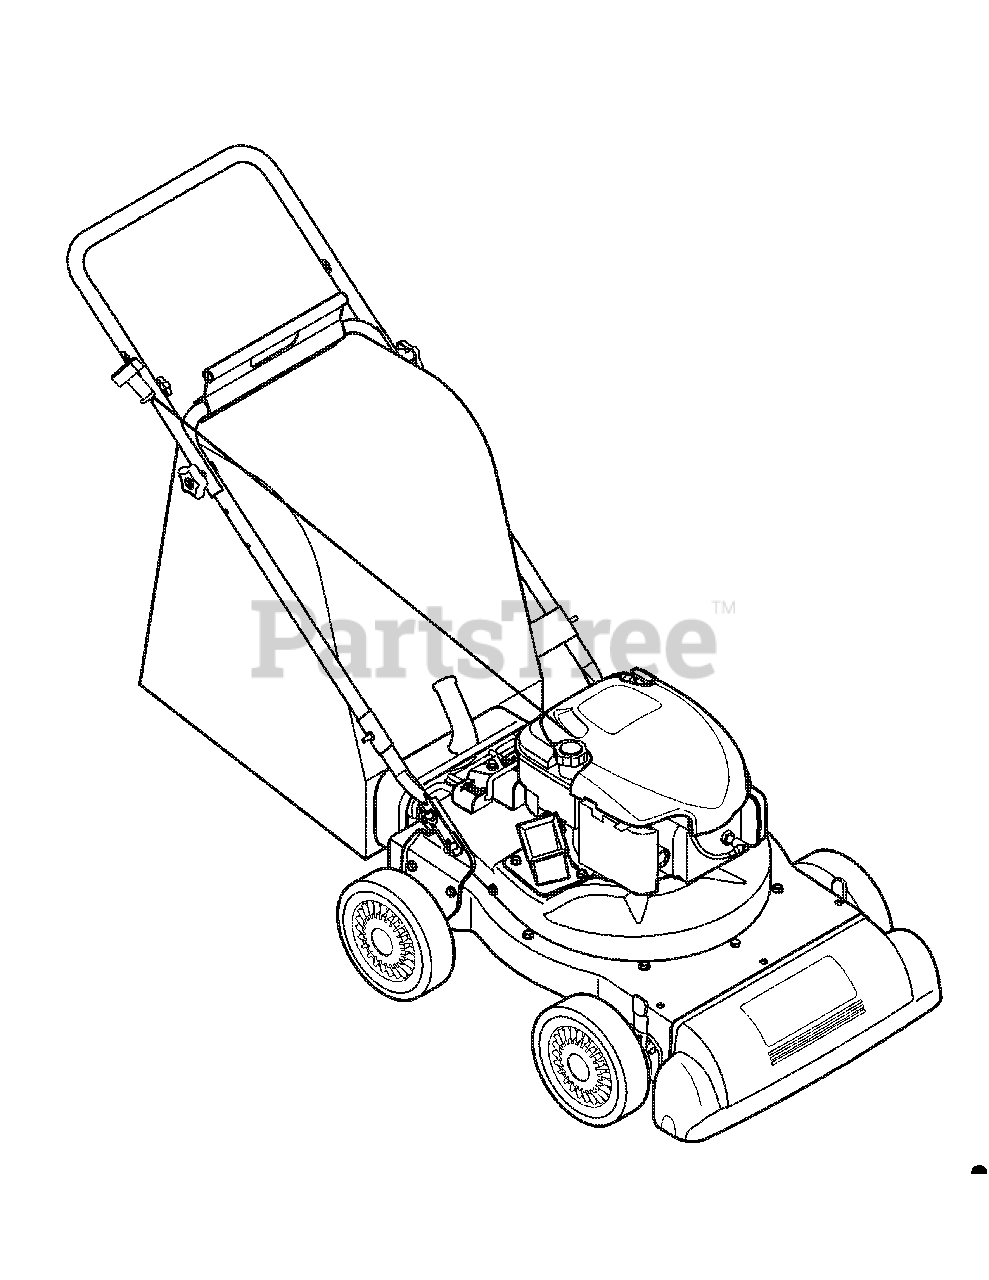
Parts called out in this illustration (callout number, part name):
NA	Drive Belt
NA	Drive Control Cable
NA	Speed Control Cable
